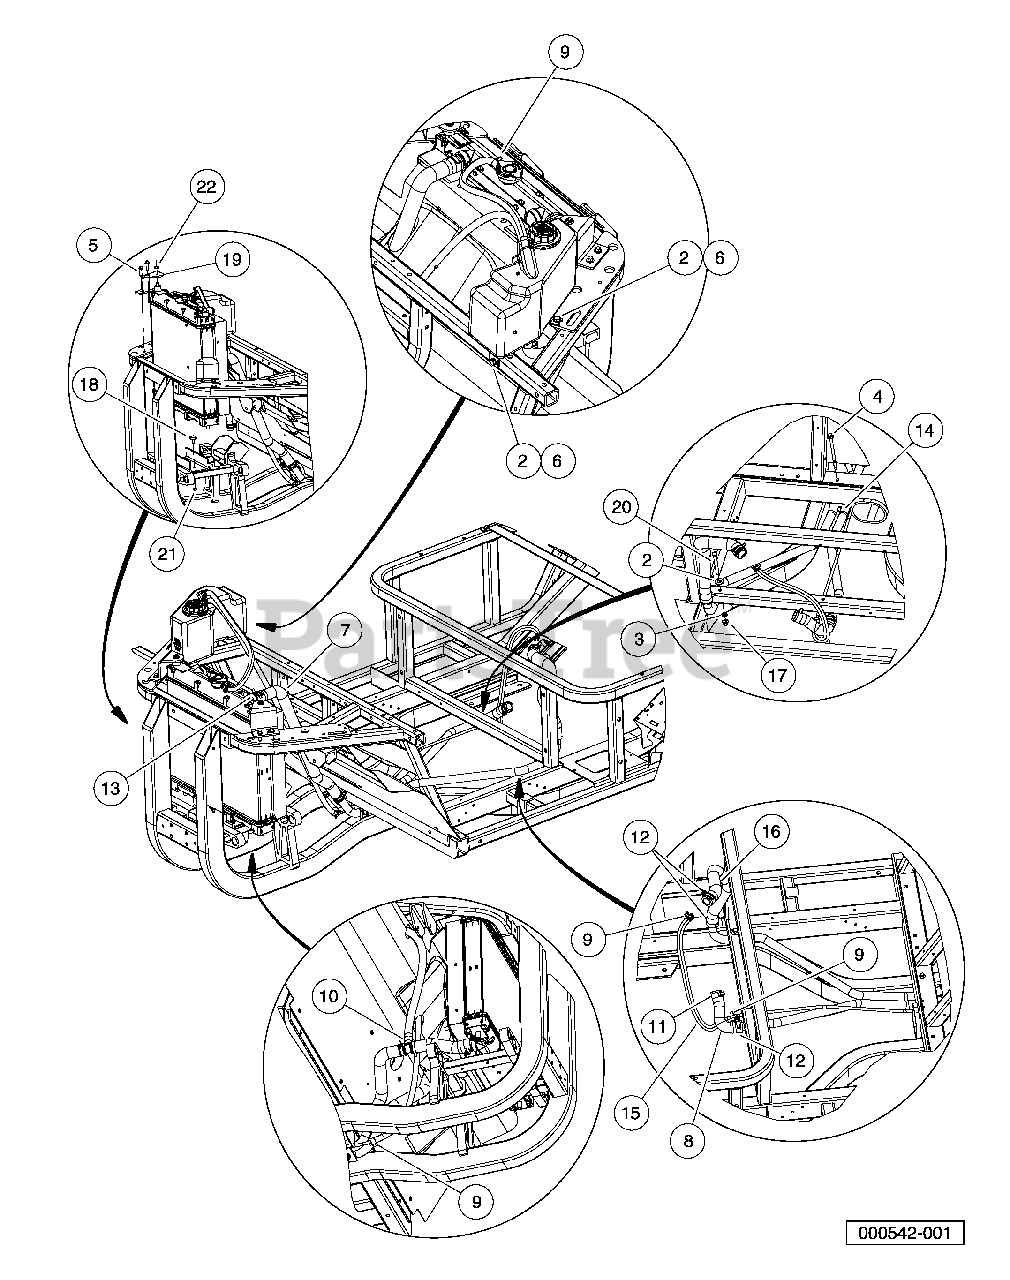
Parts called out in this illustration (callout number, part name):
1	Instl, Cooling Sys, Diesel
2	Washer, 5/16 Type B Flat
3	Spacer, 0.720"
4	Bolt-hex Fl, M8 X 1.25 X 135
5	Screw, M8X1.25X30, Hex
6	M8-1.25x20 Taptite
7	Hose, Coolant Upper Rad
8	Hose, Coolant Lower Eng
9	Clamp, Hose, CTB 15mm
10	Clamp, Hose, CTB 22mm
11	Clamp, Hose, Ctb 30mm
12	Clamp, Hose, Ctb 35mm
13	Clamp, Hose, Ctb 38mm
14	Clamp, Bar
15	Hose, Vent Tube To Eng, Coolnt
16	Hose, Coolant, Return, Engine
17	Lock Nut, Flg M8 X 1.25 Nylon
18	Bumper, 19mm Stud
19	Bracket, Radiator Support
20	Bolt, M8 X 1.25 X 110
21	Nut Flg, M6 X 1 Serrated
22	Nut Flg, M8 X 1.25 Serrated
